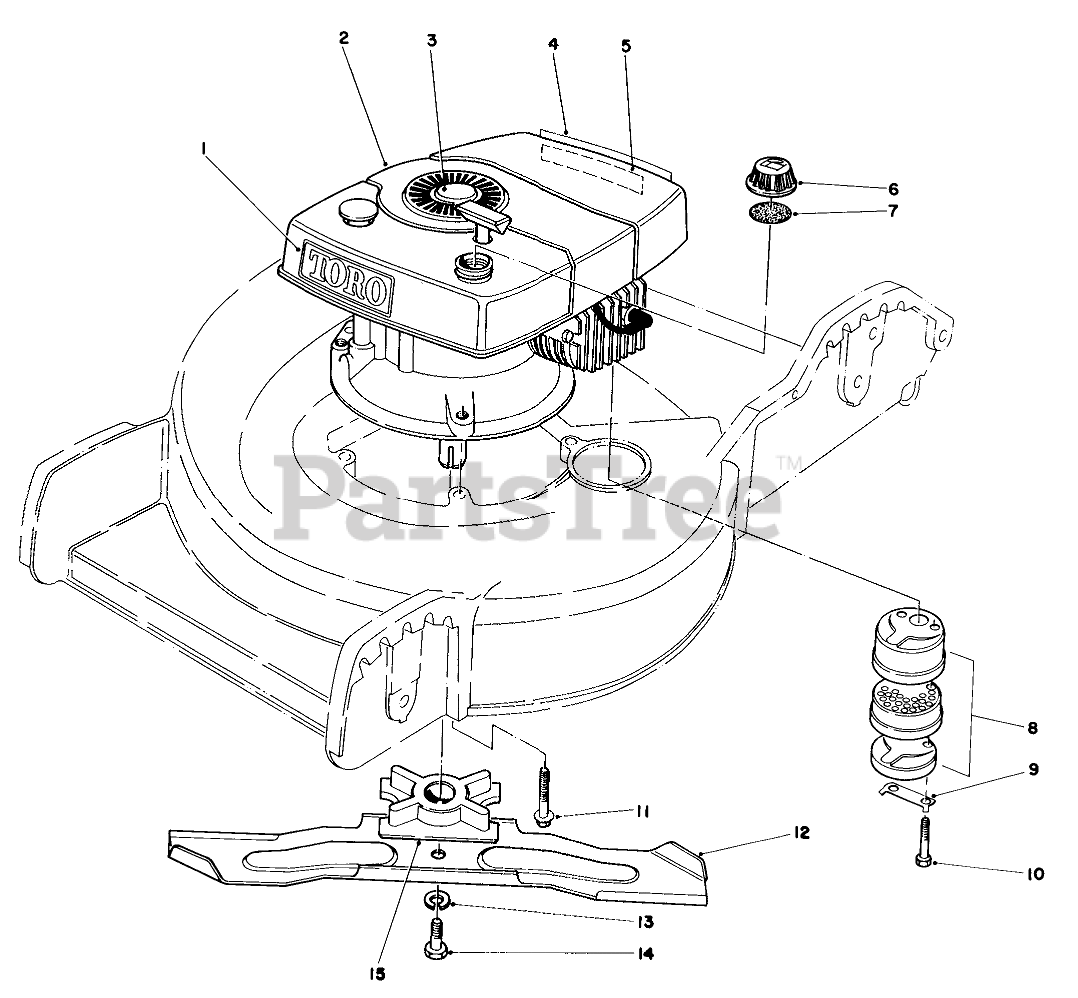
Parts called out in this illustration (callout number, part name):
1	Decal Tow
2	Engine
3	Plug Button
4	Decal-Primer
5	Decal Maintenance
6	Gas Cap Assembly (Incl. Ref. #7)
7	GAS CAP GASKET
8	Muffler Assembly (Incl. Ref. #10 & 11)
9	CLIP - LOCKING
10	SCREW-HH
11	3/8-16 X 2 CAPSCREW
12	Blade
13	WASHER-LOCK
14	SCREW-HH
15	BLADE RETAINER
